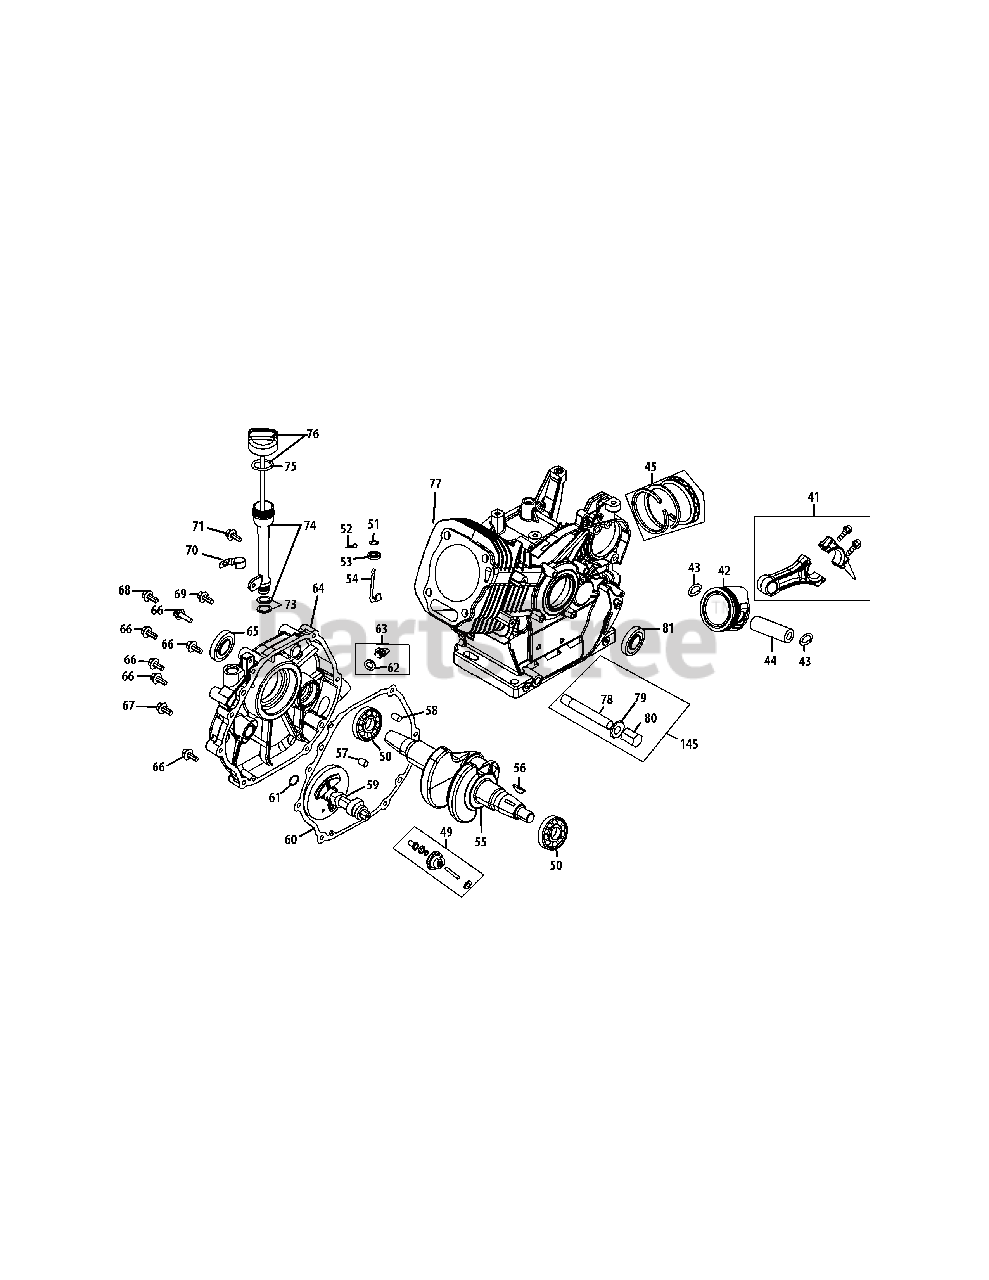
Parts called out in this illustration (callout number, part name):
41	Connecting Rod Assembly
42	Piston
43	Piston Pin Snap Ring
44	Piston Pin
45	Piston Ring Assembly
49	Governor Gear/Shaft Asm
50	Radial Ball Bearing
51	Washer 8×20×0.8
52	Cotter Pin
53	Governor Seal
54	Governor Arm Shaft
55	Crankshaft Kit
56	Woodruff Key
57	Dowel Pin 9×12
58	Dowel Pin 7×14
59	Camshaft Assy.
60	Crankcase Cover Gasket
61	Washer 16×24×0.5
62	O-Ring 15.8×2.5
63	Oil Filler Plug Assembly
64	Crankcase Cover Kit
65	Oil Seal,30×46×8
66	Bolt M8×38
67	Bolt M8×45
68	Bolt M8×35
69	Bolt M6×16
70	Oil Tube Support Bracket
71	Bolt M6×8
73	Oil Fill Tube O-Ring
74	Oil Fill Tube Asm
75	Dipstick O-Ring
76	Dipstick Asm
77	Crankcase Kit
78	Oil Drain Pipe
79	Washer 10×16×1.5
80	Oil Drain Plug
81	Oil Seal 30×46×8
126	Cylinder Baffle
127	Bolt M6×12
144	Oil Filler Plug Assembly
145	Oil Drain Assembly
